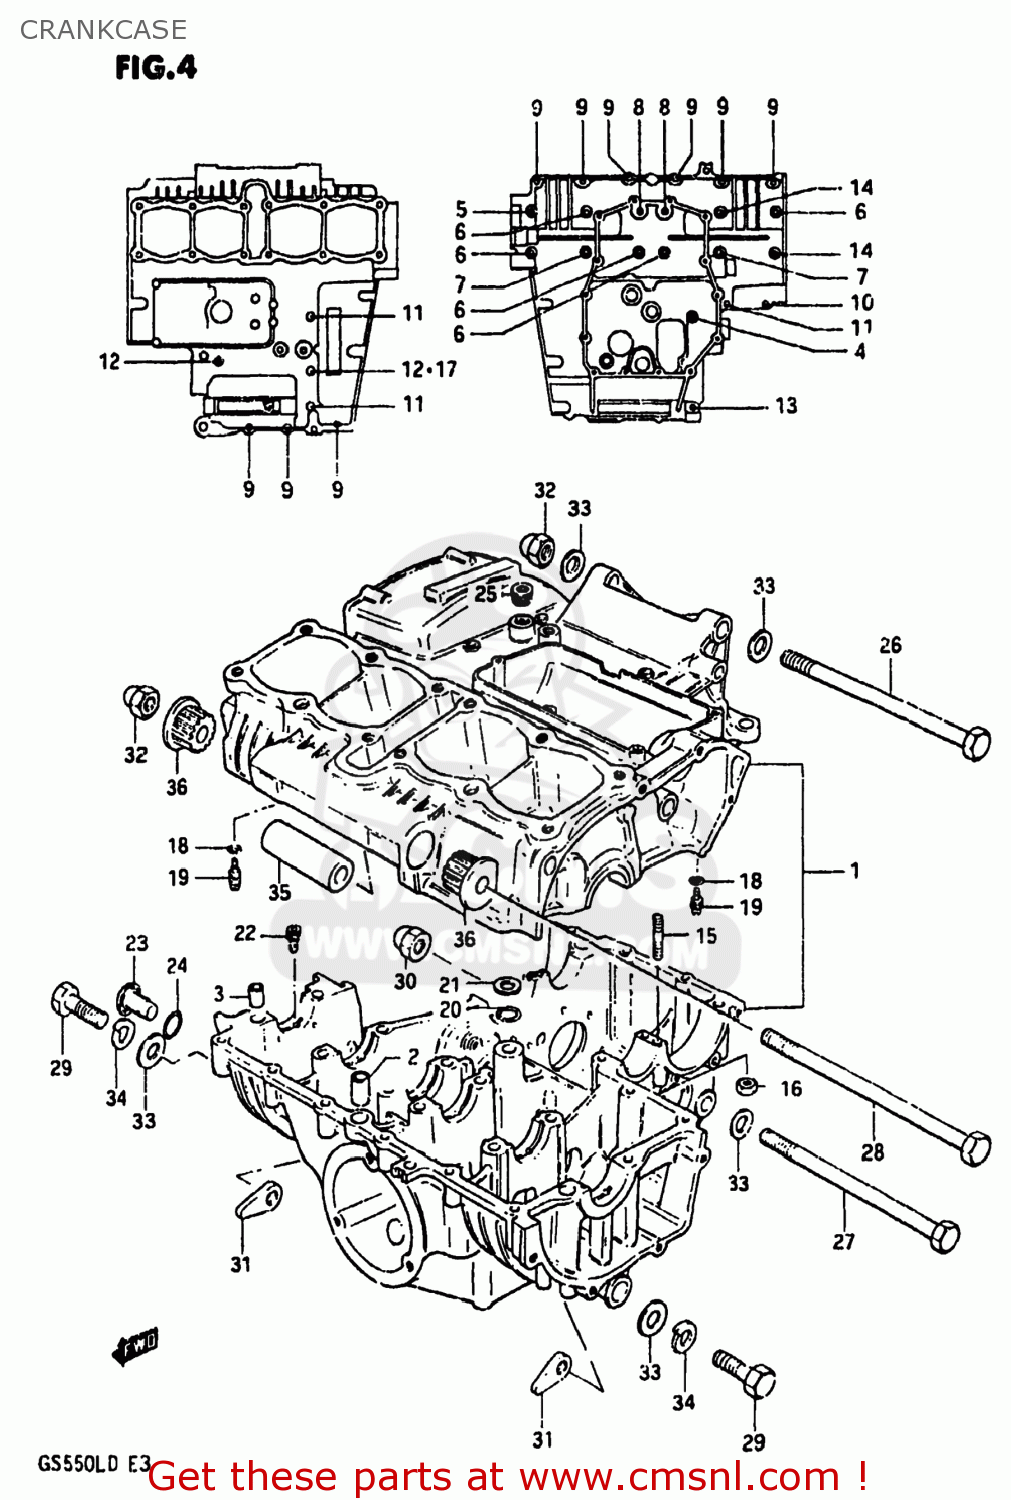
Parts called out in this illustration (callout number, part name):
1	CRANKCASE SET
2	PIN(10.4X13X22)
3	PIN (11X20)(SUS)
4	BOLT(6X100)
5	BOLT
6	BOLT
7	BOLT(8X120)
8	BOLT
9	BOLT
10	BOLT 6X55
11	BOLT
12	BOLT (5X95)
13	BOLT 8X60
14	BOLT (8X90)
15	STUD BOLT
16	NUT
17	GASKET(6.2X13X1.2) (NAS)
18	O RING(D:1.2,ID:4)
19	JET,OIL GALLERY
20	O RING(D:3.2,ID:12.9)
21	WASHER,THRUST
22	JET,AIR
23	PLUG
24	O RING(D:2.4,ID:16.8)
25	PLUG
26	BOLT
27	BOLT
28	BOLT
29	BOLT
30	NUT 10MM
31	NUT
32	NUT
33	WASHER
34	LOCK WASHER
35	SPACER (10.2X16X105.5)
36	BUSH
